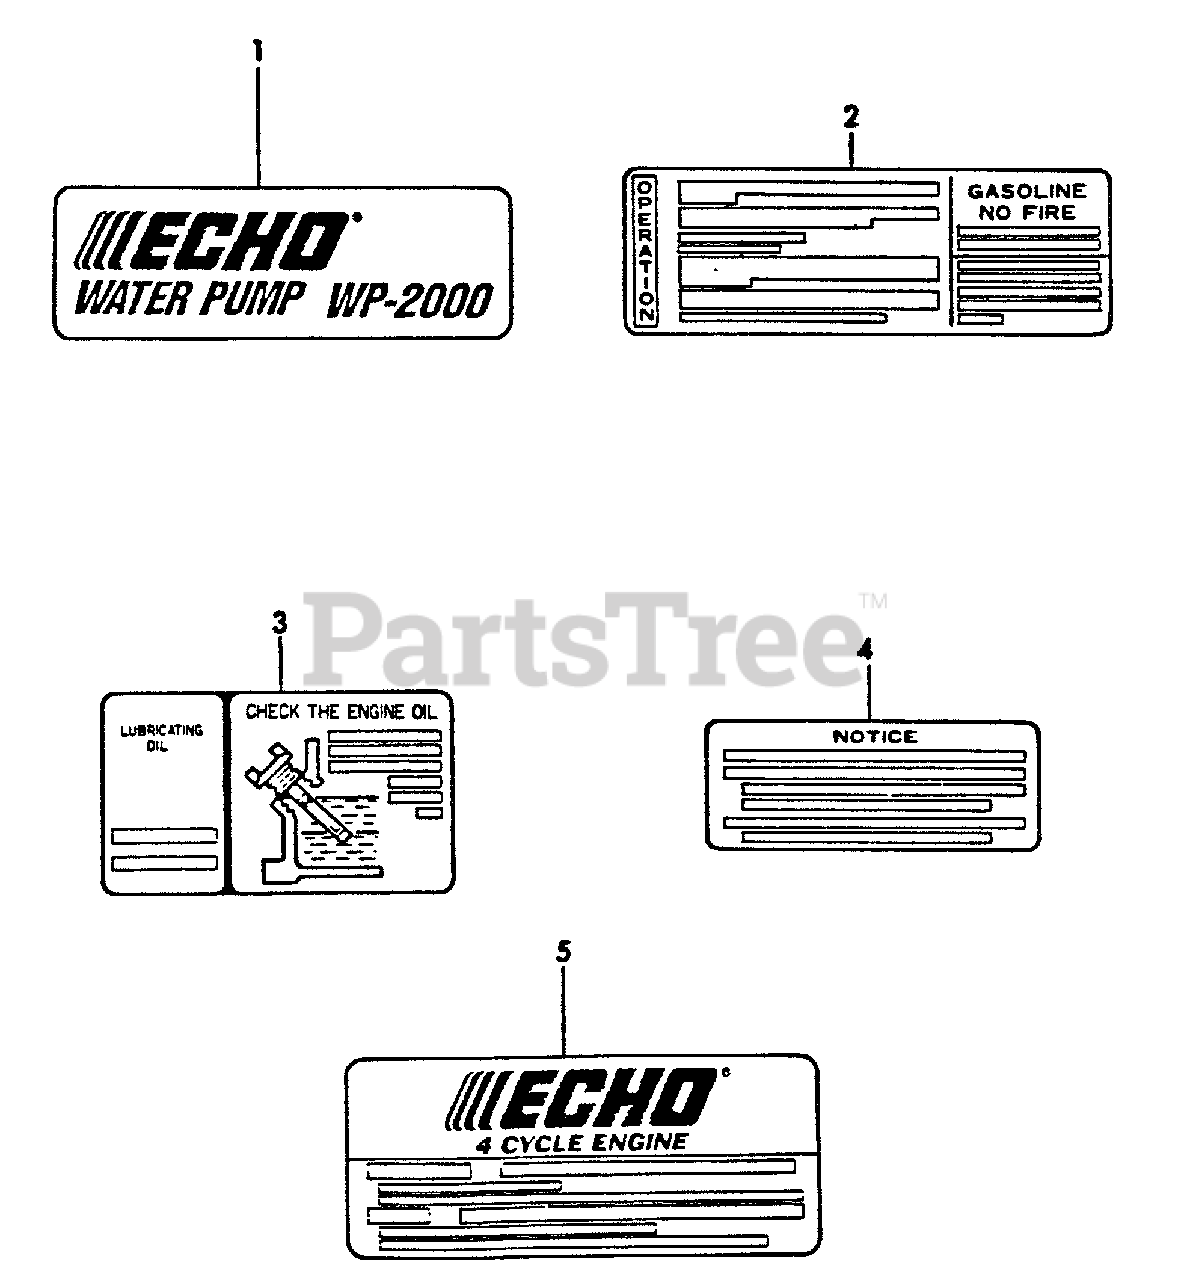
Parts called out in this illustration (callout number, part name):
1	LABEL - MODEL WP2000
2	LABEL, OPERATION
3	LABEL, OIL
4	LABEL - AIR FILTER
5	LABEL - ECHO
